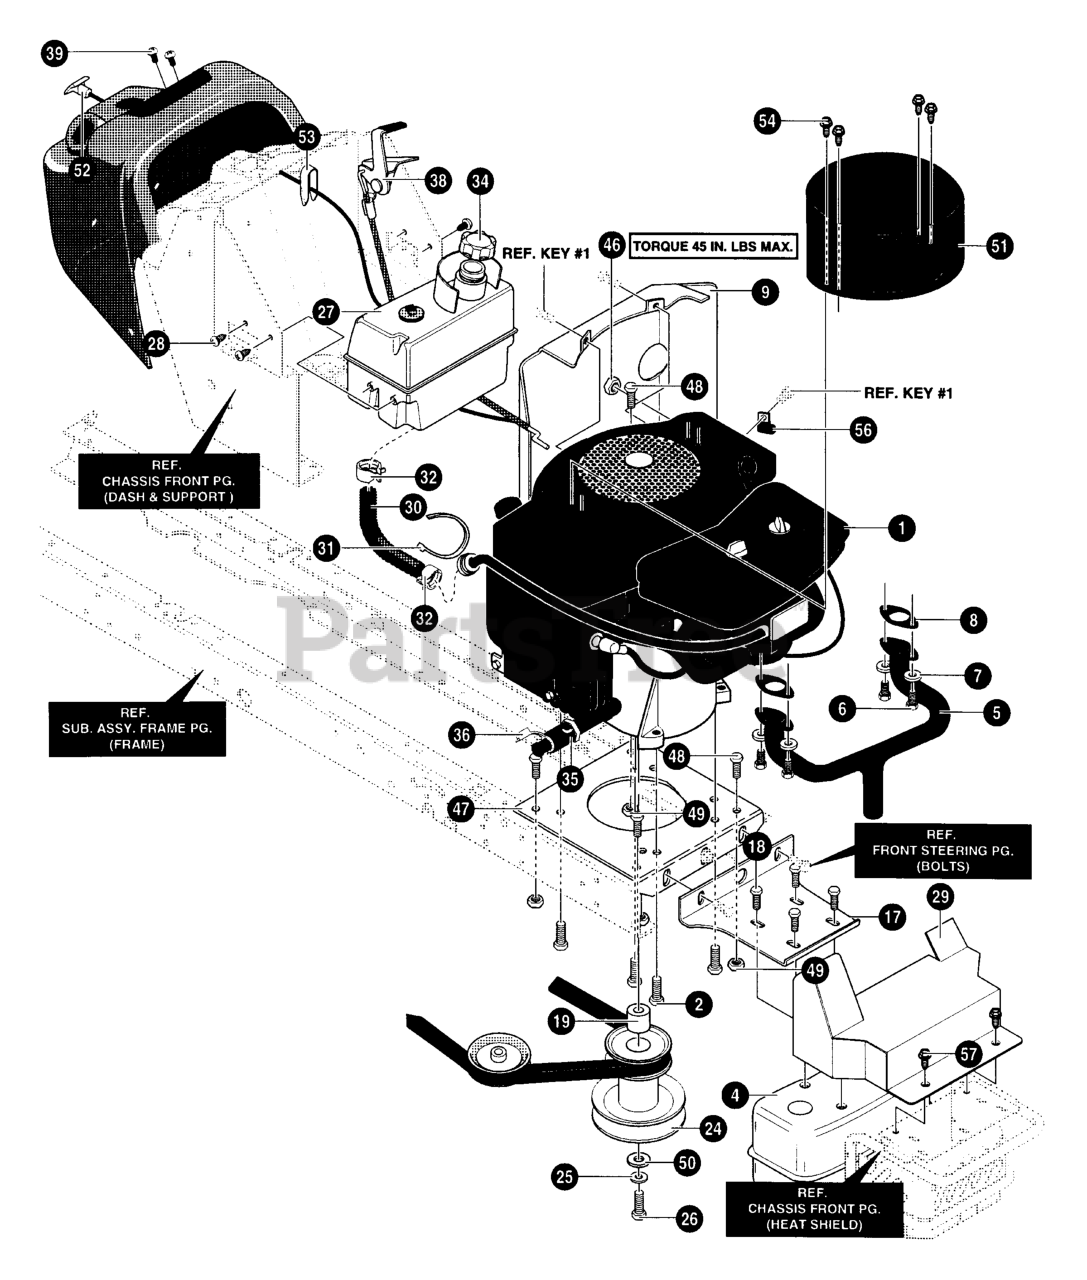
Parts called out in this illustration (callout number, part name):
1	ENGINE 15HP BS OHV IC
2	SCREW, 3/8- 16X1.25
4	MUFFLER, SINGLE- CYLINDER
5	EXHAUST MANIFOLD
7	WASHER
8	GASKET, Exhaust
9	SHIELD, HEAT
17	BRACKET, MUFFLER MOUNT
18	SCREW, 1/4-20X.75
19	SPACER, SLEEVE
24	PULLEY, STACK ASSY
27	TANK, FUEL 2.8 GAL.
29	HEAT SHIELD
30	Fuel Line (Must cut to length)
31	CABLE TIE
32	CLAMP, GAS
34	CAP, FUEL
35	OIL DRAIN
36	CAP, OIL DRAIN
38	THROTTLE CONTROL
39	SCREW, #8- 16X.50
46	NUT 1 /4- 20
47	PLATE, ENGINE
48	SCREW, 5/16-18 x 0.75
49	NUT, 5/16- 18
50	FLATWASHER
51	PLENUM, ENGINE
52	CHOKE CONTROL
53	CLIP, CHOKE CONTROL
54	SCREW 10- 16X0.5
56	RETAINER, WIRE
